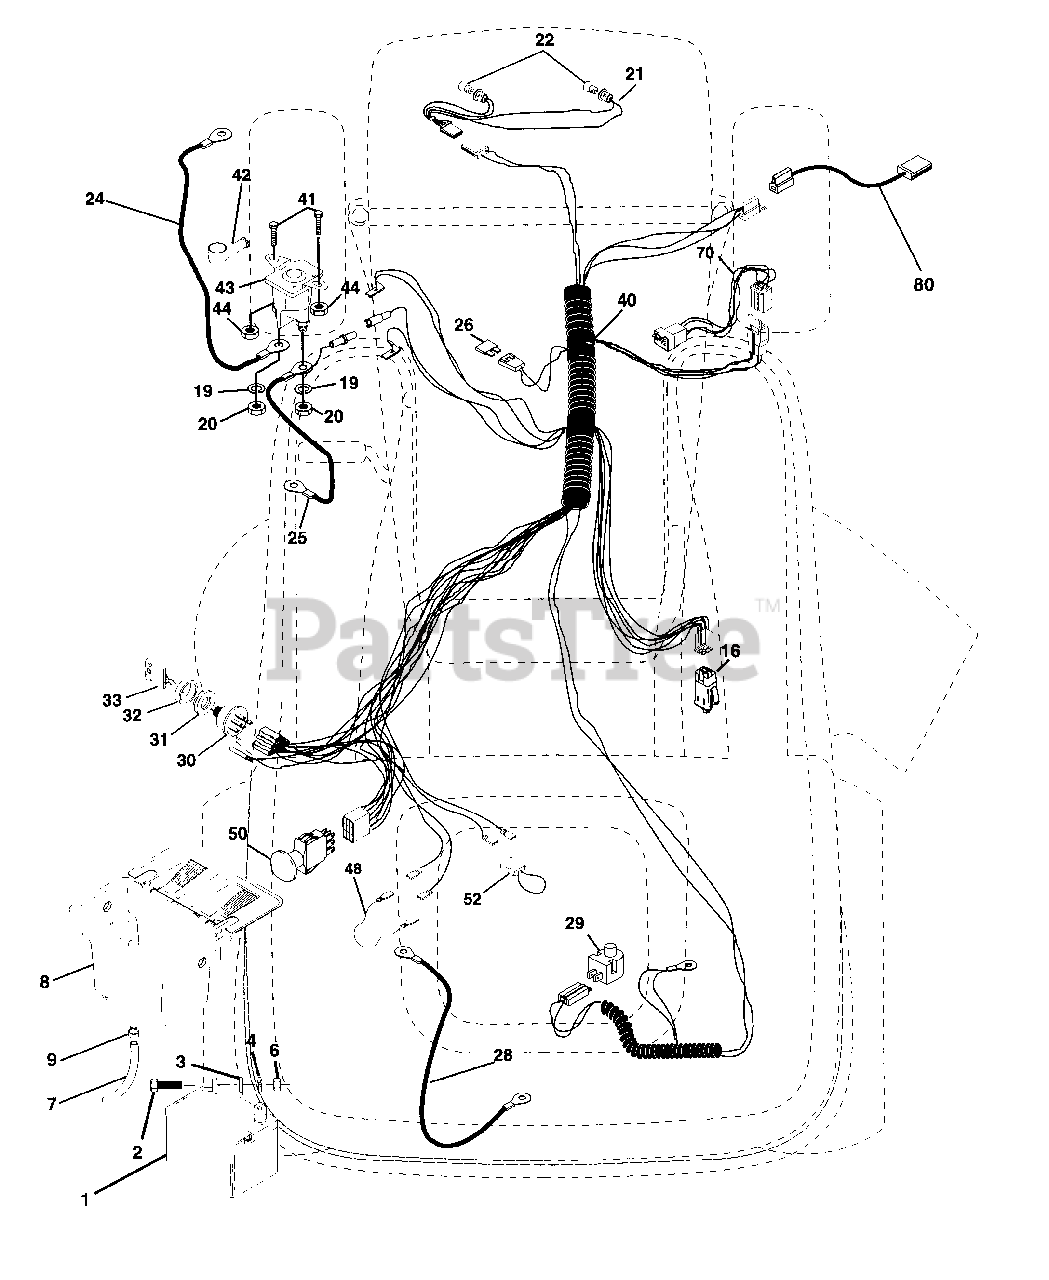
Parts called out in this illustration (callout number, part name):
1	Battery 12 Volt 25 AMP
2	Bolt Hex Hd 1/4-20unc X 3/4
3	Washer 9/32 X 5/8 X 16 Ga.
4	Washer Lock Hvy Helical 1/4
6	Nut Fin Hex 1/4-20 Unc
7	Tube Plastic 12"
8	Case Battery Mech Hinge
9	Clamp Hose Olive
16	Switch Interlock Push-In
19	Washer Lock 1/4
20	Nut Jam Hex 1/4-20 Unc
21	Harness Asm Light W/4152j
22	Bulb Light #1156
24	Cable Battery 6 Ga 11" red
25	Cable Battery 6 Ga 44" red w/16 wire
26	Fuse 30 AMP Auto Green
28	Cable Ground 6 Ga 12" black
29	Switch Plunger Nc Gray
30	Switch Ign 4 pos w/lights
31	Nut Ignition
32	Cover Sw Ignition
33	Key Ign Modelled Generic
40	Harness Ign.
41	Bolt Blk Fin Hex 1/4-20 x 1/2
42	Cover Terminal Red
43	Solenoid
44	Nut Keps Hex 1/4-20 Unc
48	Adapter Ammeter Rectangular
50	Switch PTO 3PDT Black Delta 96
52	Protection Wire Loop
70	Harness, Eng. kohl Cmd-L Dual
80	Harness Clutch EVX
